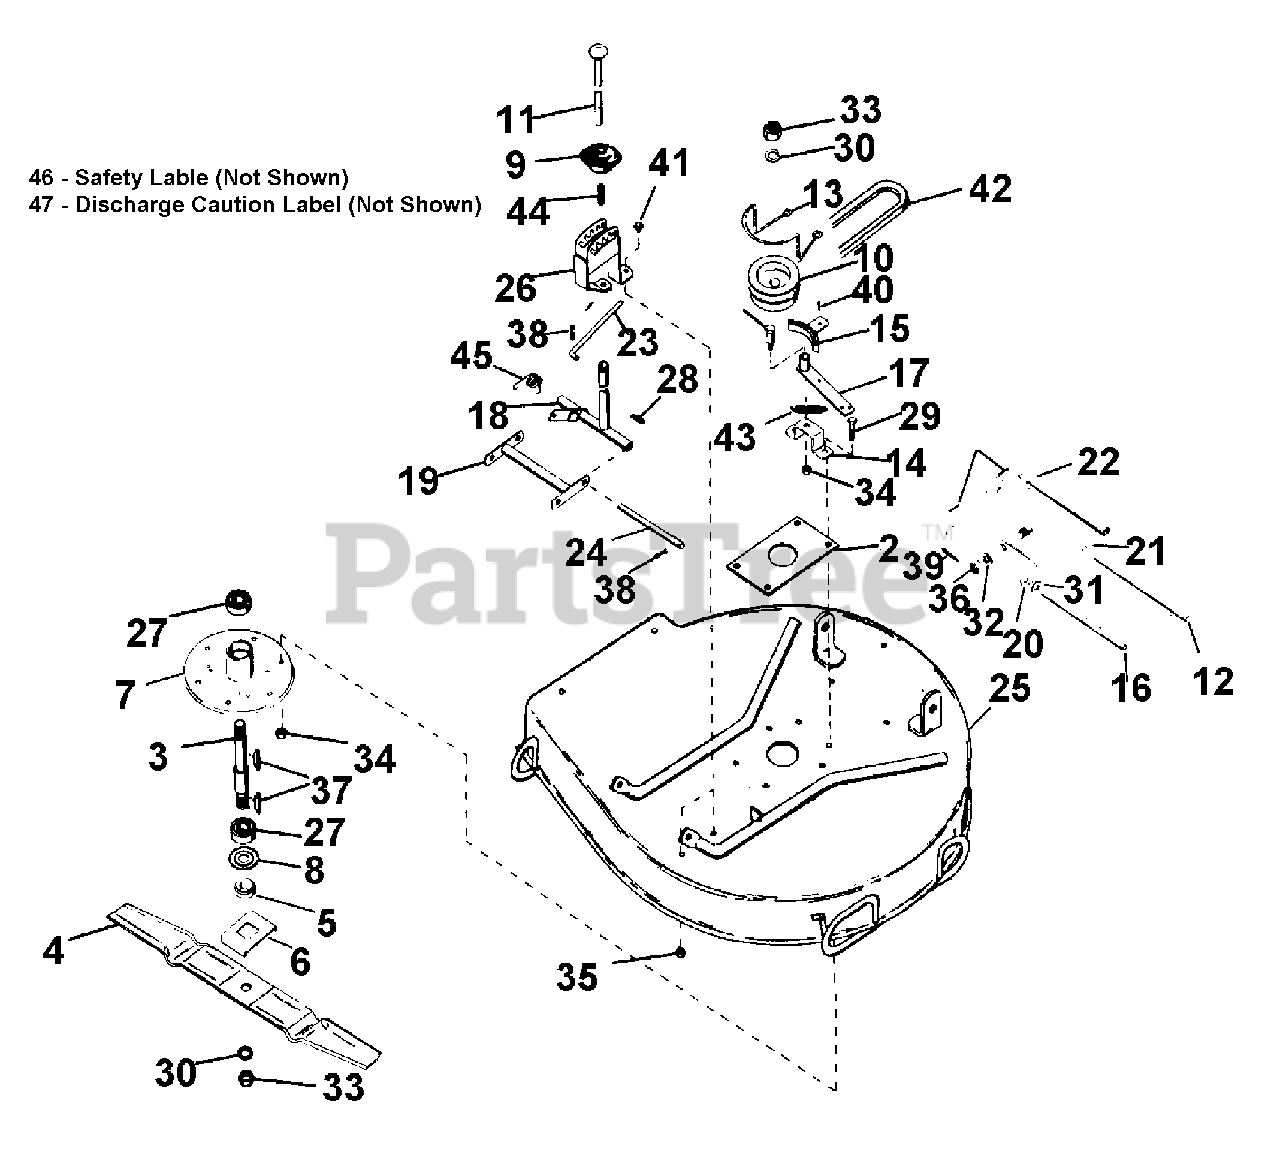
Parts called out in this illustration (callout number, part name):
1	SHOULDER BOLT .50 X 1.75
3	MOWER SPINDLE
4	BLADE, MOWER
5	RETAINER HUB
6	BLADE TRAY
7	SPINDLE HOUSING
8	BEARING SLINGER
9	SHIFT BALL
10	MOWER SHEAVE
11	HGHT CNTL PLNGR
12	REAR BRACKET PIN
13	MOWER BELT FINGER
14	BLADE BRAKE SUPPORT
15	BLADE BRAKE
16	HANGER PIN
17	BLADE BRAKE ARM
18	HGHT CNTL ARM
19	FLOATING LINK
22	REAR RAISING BRACKET
23	HGHT LINK ROD
24	ADAPTER PIN
25	MOWER PAN
26	MWR HGHT QUAD
27	BRG-BALL .751X1.78X.61
28	PIN-ROLL .250X1.25
29	BLT-HEX .38-16X1.00 PL
30	WSHR-LK .750X.188 MED PL
31	WSHR-FL-STL .531X1.062X.095 PL
32	WSHR-FL-STL .630X1.005X.062 PL
33	NUT-JAM .75-10 PL
34	NUT-LK-CTR .375-16 GR A PL
35	NUT-LK .312-18 GR A PL
36	NUT-JAM-SL .625-18
37	KEY-WDRF .188X.75X.313 SAE 9
38	PIN-COTR .12X1.0 PL
39	PIN-COTR .12 X 1.25 PL
40	RVT .25X.50 RH ST
41	BLT-SERHFWH .31-18X.50 PL
42	V-BELT, 5L-RAW EDGE
43	SG-TENS .072X.51X5.31 WLD 25
44	SG-COMP ??X.44X?? WLD 10
45	SG-TORS .162X.75X.648
